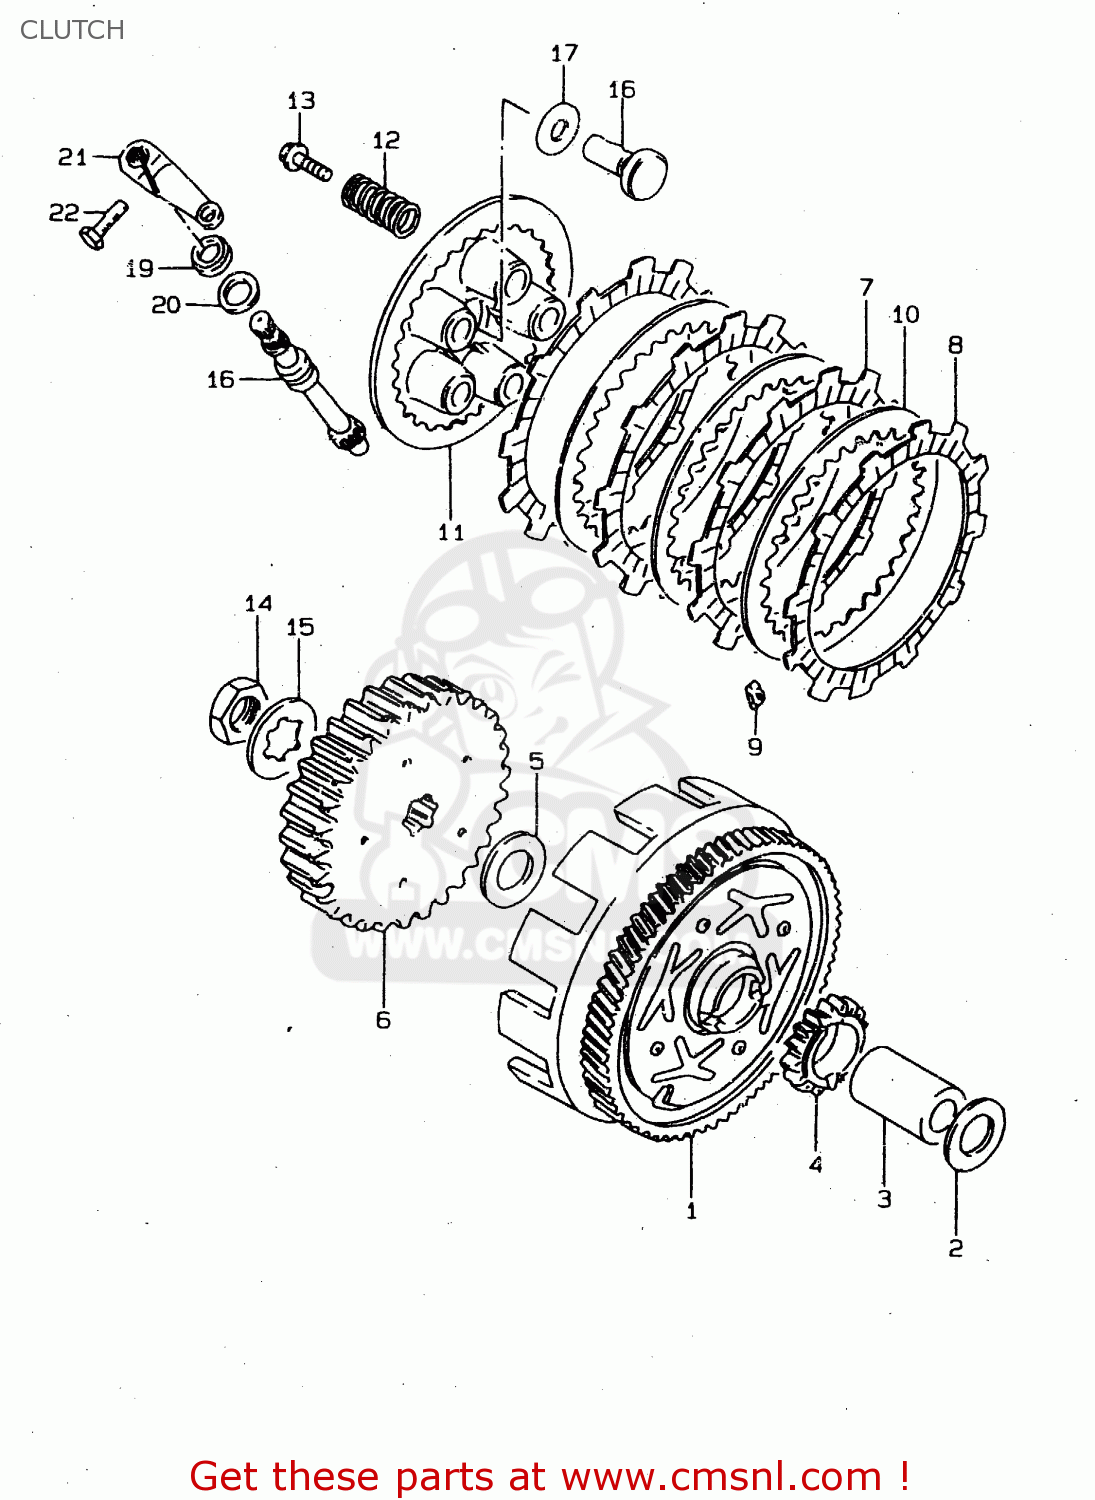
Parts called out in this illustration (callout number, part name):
1	GEAR ASSY,PRI DRIVEN(NT:73)
2	WASHER,THRUST
3	SPACER,PRIMARY DRIVEN GEAR
4	GEAR,KICK STARTER DRIVE
5	WASHER
6	HUB,CLUTCH SLEEVE
7	PLATE,CLUTCH DRIVE(T:3.0) (NAS)
8	PLATE,CLUTCH DRIVE (NAS)
9	DAMPER
10	PLATE,CLUTCH DRIVEN (NAS)
11	DISC,CLUTCH PRESSURE
12	SPRING
13	BOLT 5X16
14	NUT
15	WASHER,LOCK
16	RACK,CLUTCH RELEASE
17	BEARING(10X22X2.8)
18	PINION,CLUTCH RELEASE
19	SEAL,OIL(10X17X5)
20	WASHER
21	ARM,CLUTCH RELEASE
22	BOLT
